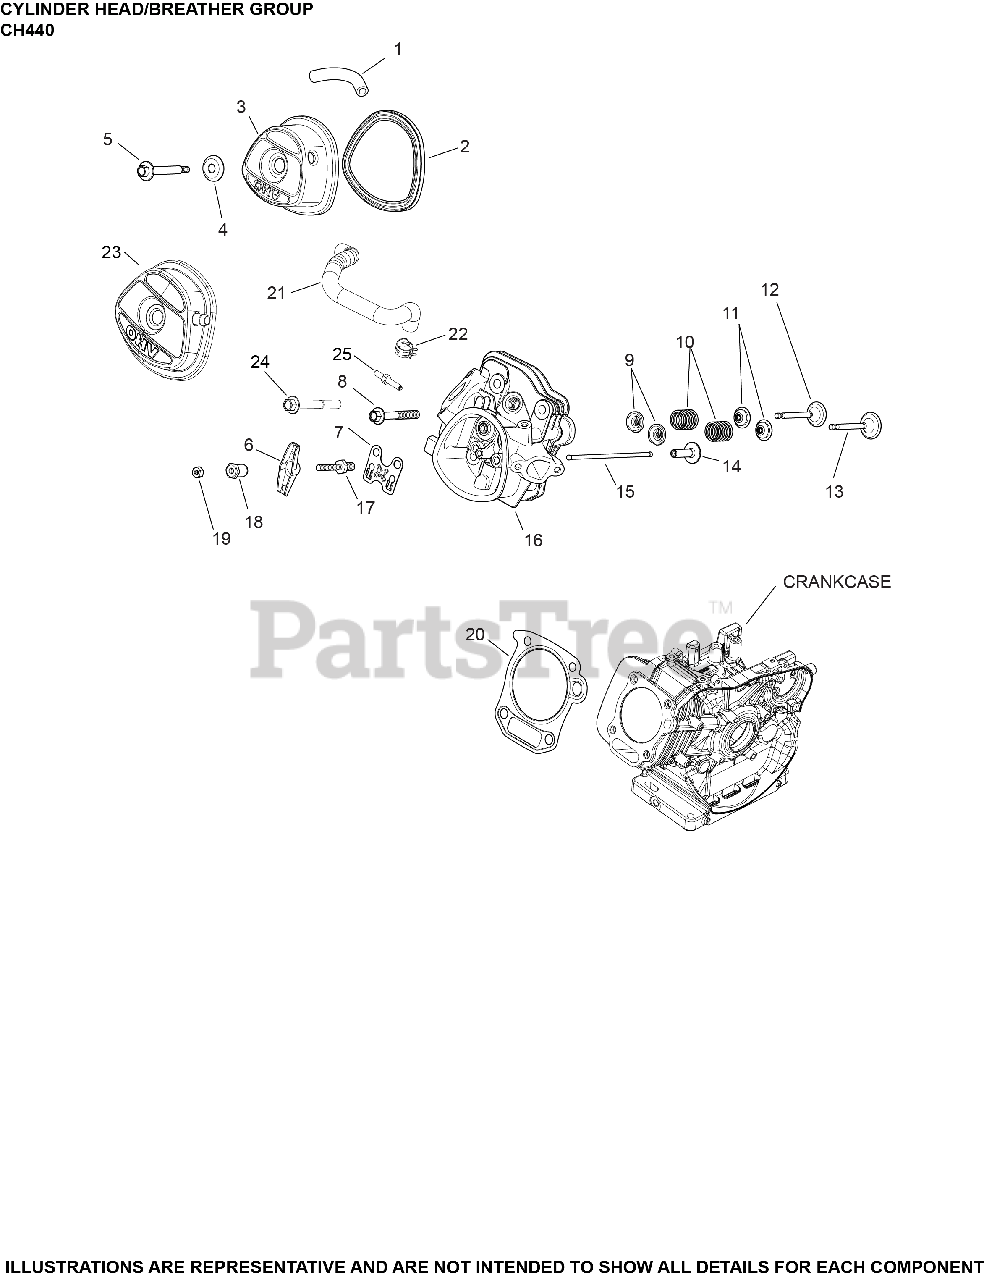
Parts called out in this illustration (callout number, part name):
1	TUBE, BREATHER
2	GASKET, VALVE COVER
3	KIT, VALVE COVER ASSEMBLY
5	SCREW, VALVE COVER SEAL ASSY
6	ARM, ROCKER
7	PLATE, PUSHROD GUIDE
8	SCREW, HEX FLANGE CYLINDER HEAD (CKY)
9	RETAINER, VALVE SPRING
10	SPRING, VALVE
11	SEAL, VALVE STEM
12	VALVE, EXHAUST
13	VALVE, INTAKE
14	LIFTER, VALVE
15	ROD, PUSH
16	KIT, CYLINDER HEAD
17	STUD, ROCKER ARM - (#1407222S)
18	PIVOT, ROCKER ARM
19	NUT, HEX JAM
20	KIT, HEAD GASKET
